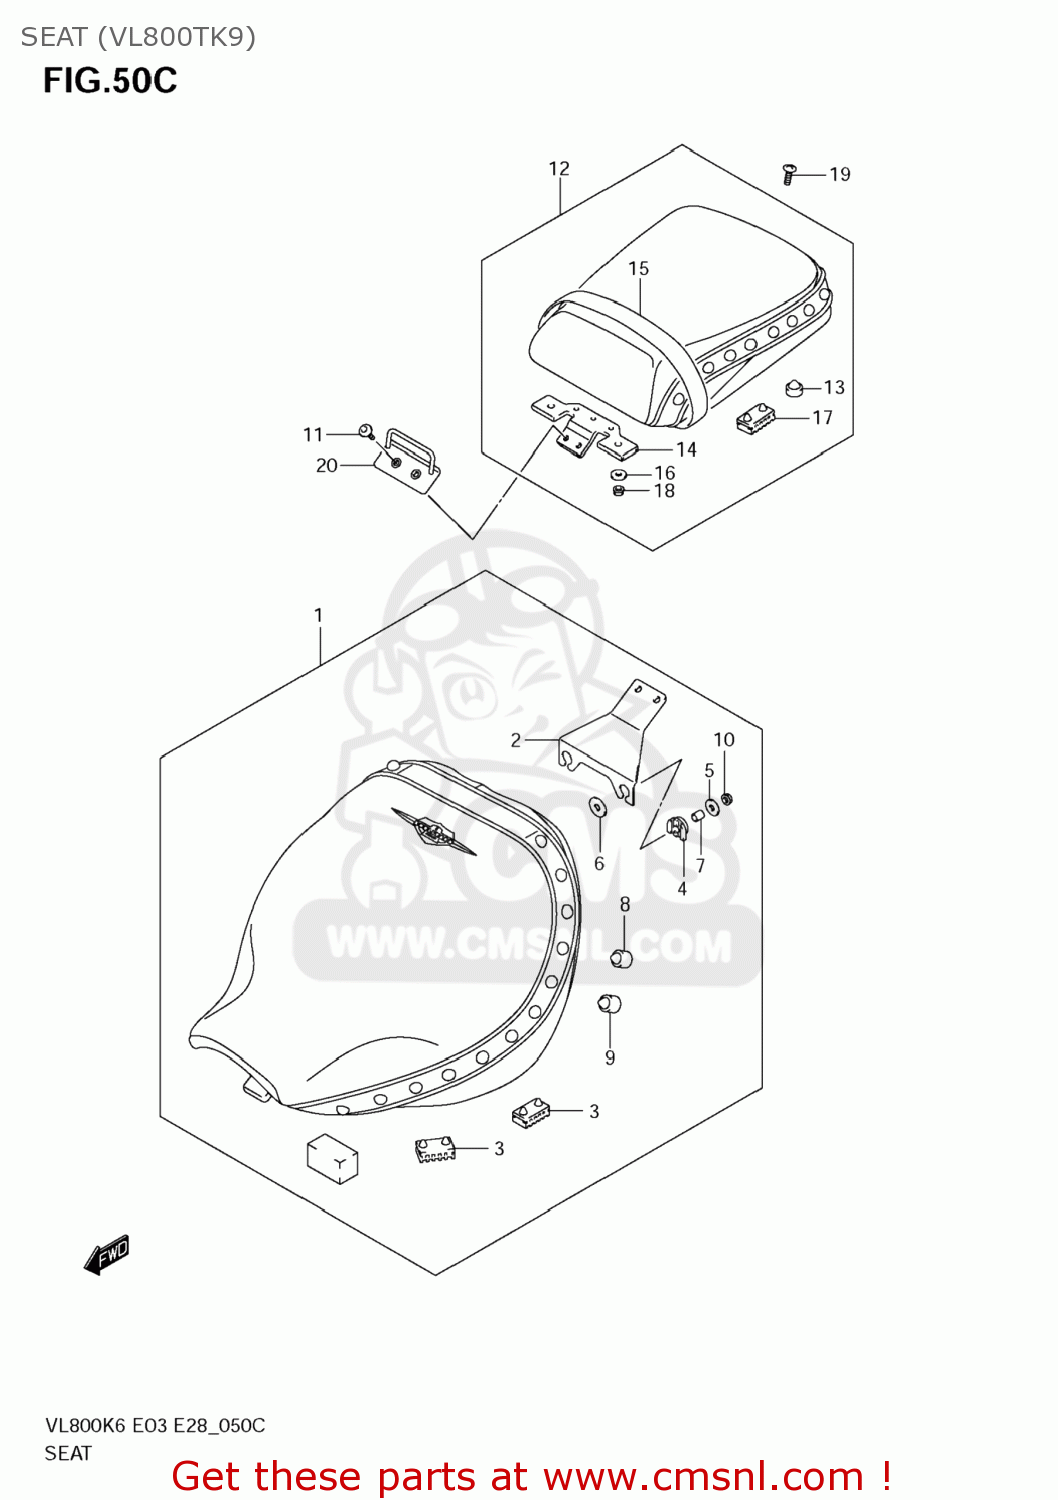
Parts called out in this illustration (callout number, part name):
1	SEAT ASSY
2	BRACKET,SEAT
3	CUSHION,SEAT(40X20X15)
4	CUSHION,SEAT BRACKET
5	WASHER(6.5X20X1.6)
6	WASHER(6.5X24X1.6)
7	SPACER(6.5X10X11)
8	CUSHION(11.5X22X20)
9	CUSHION
10	NUT
11	BOLT(6X18)
12	SEAT ASSY,PILLION
13	CUSHION,RR
14	BRACKET,PILLION SEAT
15	BAND, SEAT PILLION
16	WASHER(6.5X20X1.6)
17	CUSHION(11.5X22X20)
18	NUT
19	BOLT(8X16)
20	BRACKET,SEAT SUPPORT
